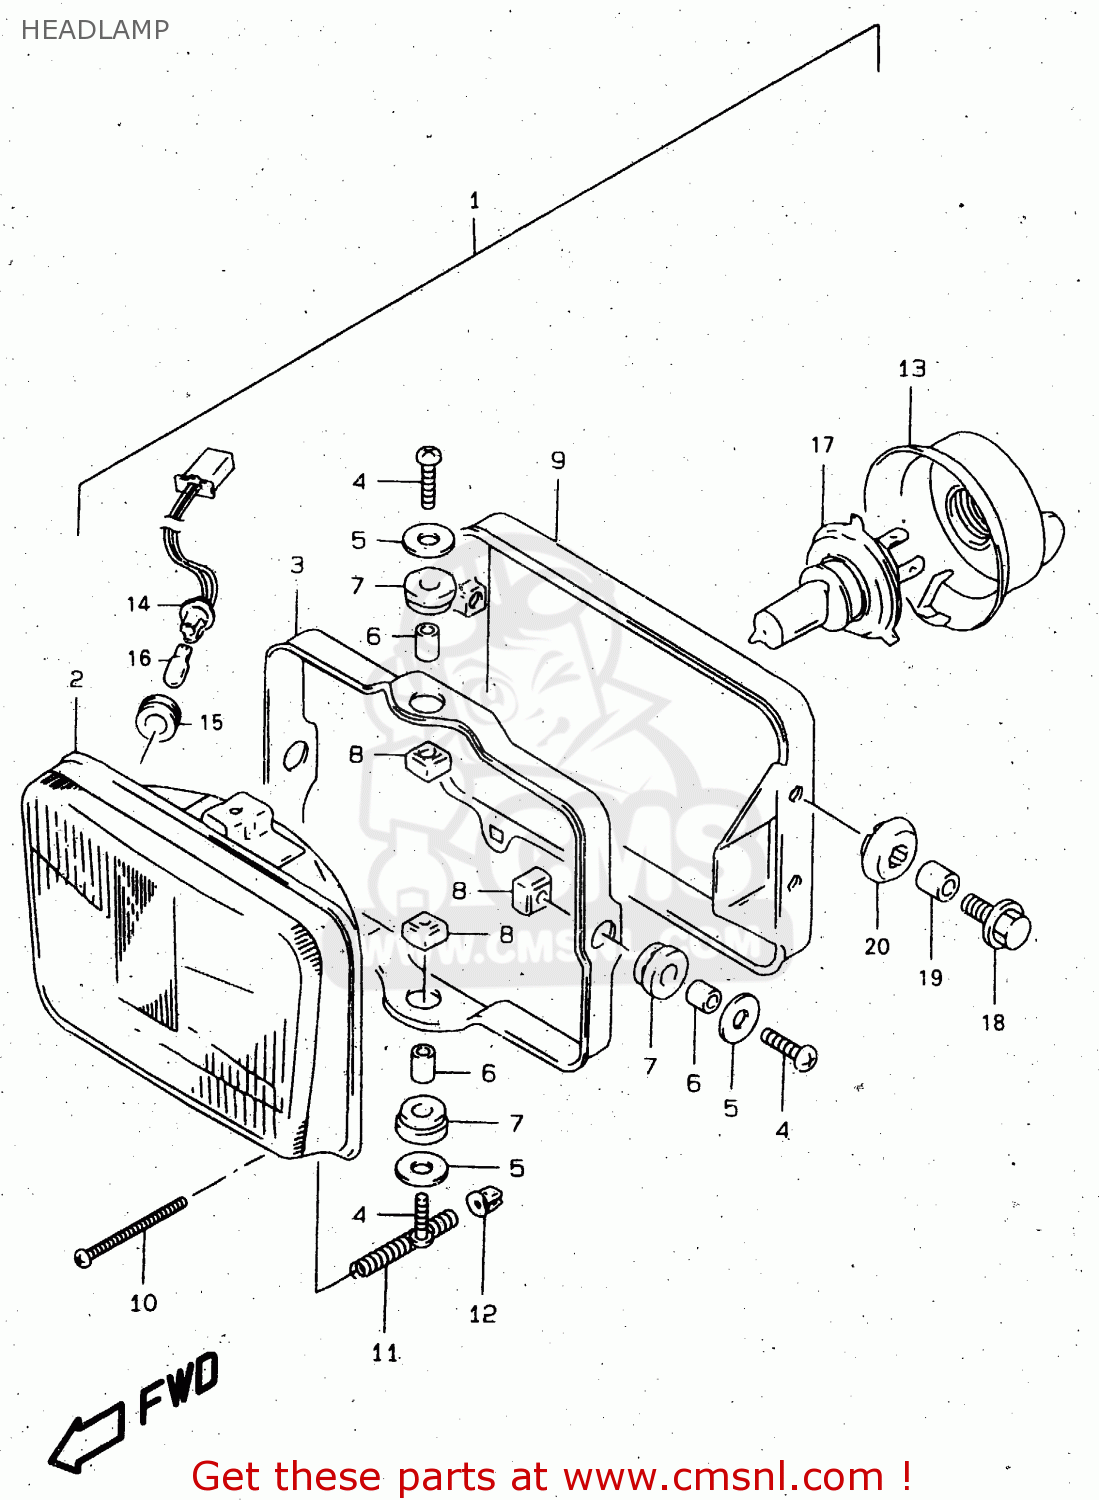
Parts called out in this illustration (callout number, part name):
1	HEADLAMP ASSY
2	UNIT ASSY
3	RING,MOUNTING
4	SCREW
5	WASHER(5.5X18X1)
6	SPACER
7	CUSHION
8	NUT
9	HOUSING
10	SCREW(4X45)
11	SPRING,ADJUSTING
12	NUT,ADJUSTING
13	COVER,SOCKET
14	CORD,POSITION
15	JOINT,RUBBER
16	BULB(12V4W)
17	BULB(12V60/55W,H4)
18	BOLT(6X20)
19	SPACER(6.5X10X10)
20	CUSHION
